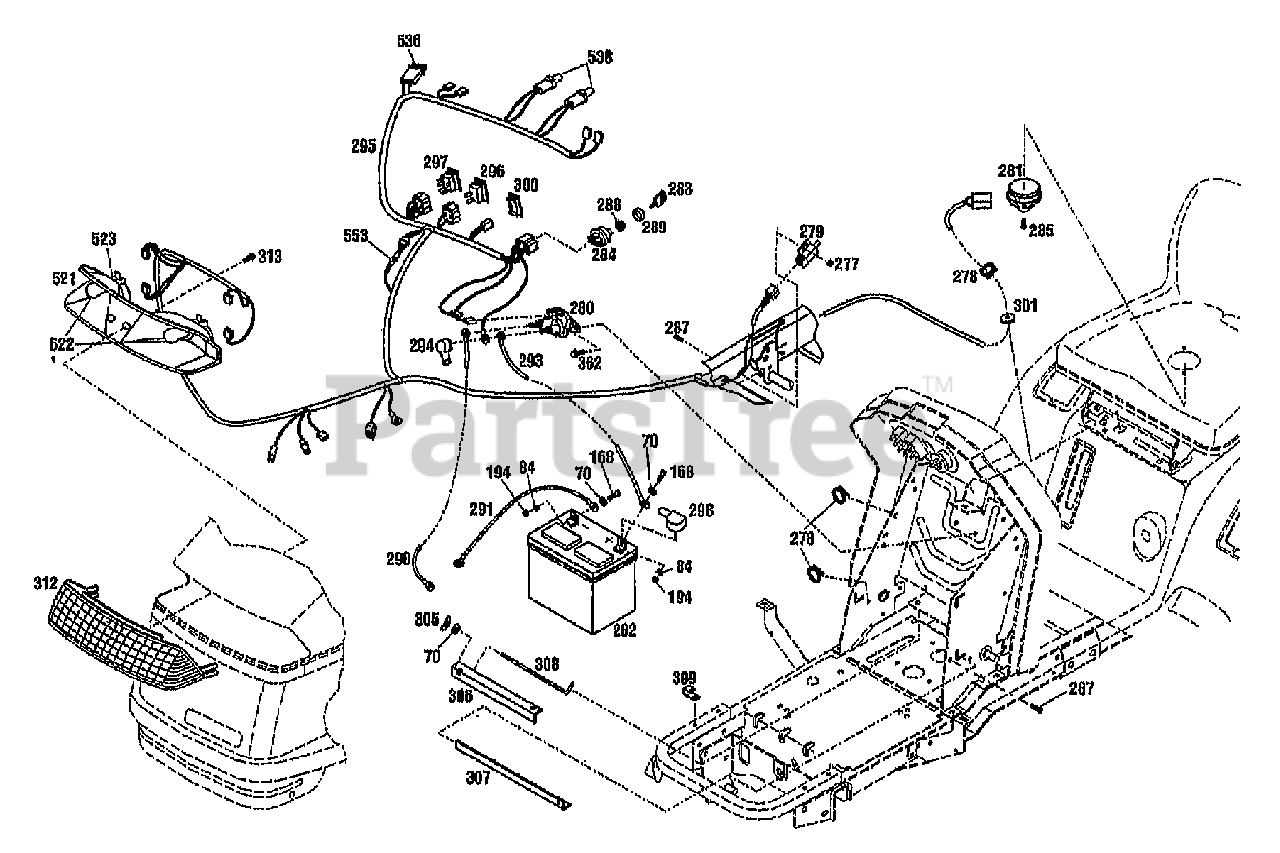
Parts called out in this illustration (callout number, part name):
70	WASHER-FLAT 1/4 SAE
84	WASHER-LK .25 ZP
168	SCR-HH 1/4-20X.75 G5 ZP
194	NUT-HEX 1/4-20 ZP
277	NUT W/LKWASHER 10-24 ZP
278	TIE-CABLE NYLON BLACK
279	SWITCH
280	SOLENOID
281	SWITCH-SEAT
282	BATTERY
283	KEY-IGNITION
284	SWITCH-IGNITION
285	SCR-PHP 1/4-20X.50 ZP
287	SCR-HHS 10-24X.625 ZP
288	NUT-SWITCH
289	CAP-SWITCH
290	CABLE-STARTER
291	CABLE-BATTERY (-)
293	CABLE-BATTERY
294	BOOT-SOLENOID
295	HARNESS-MAIN
296	SWITCH-LIGHT
297	SWITCH-PTO
298	BOOT-TERMINAL
300	COVER-SWITCH
301	GROMMET
305	NUT-WING
306	CLAMP-BATTERY
307	BRKT-BATTERY LOWER
308	SCR-HOOK
309	CLIP-J
312	LENSE-HEADLIGHT
362	SCR 1/4-20X.5 FL SELF TAP
521	ASSM-HEADLIGHT
522	LIGHTBULB
523	SOCKET
536	FUSE
538	LIGHTBULB
553	ASSM-DIODE
600	PAINT-BLACK SPRAY
601	PAINT-RED SPRAYCAN POWDER
